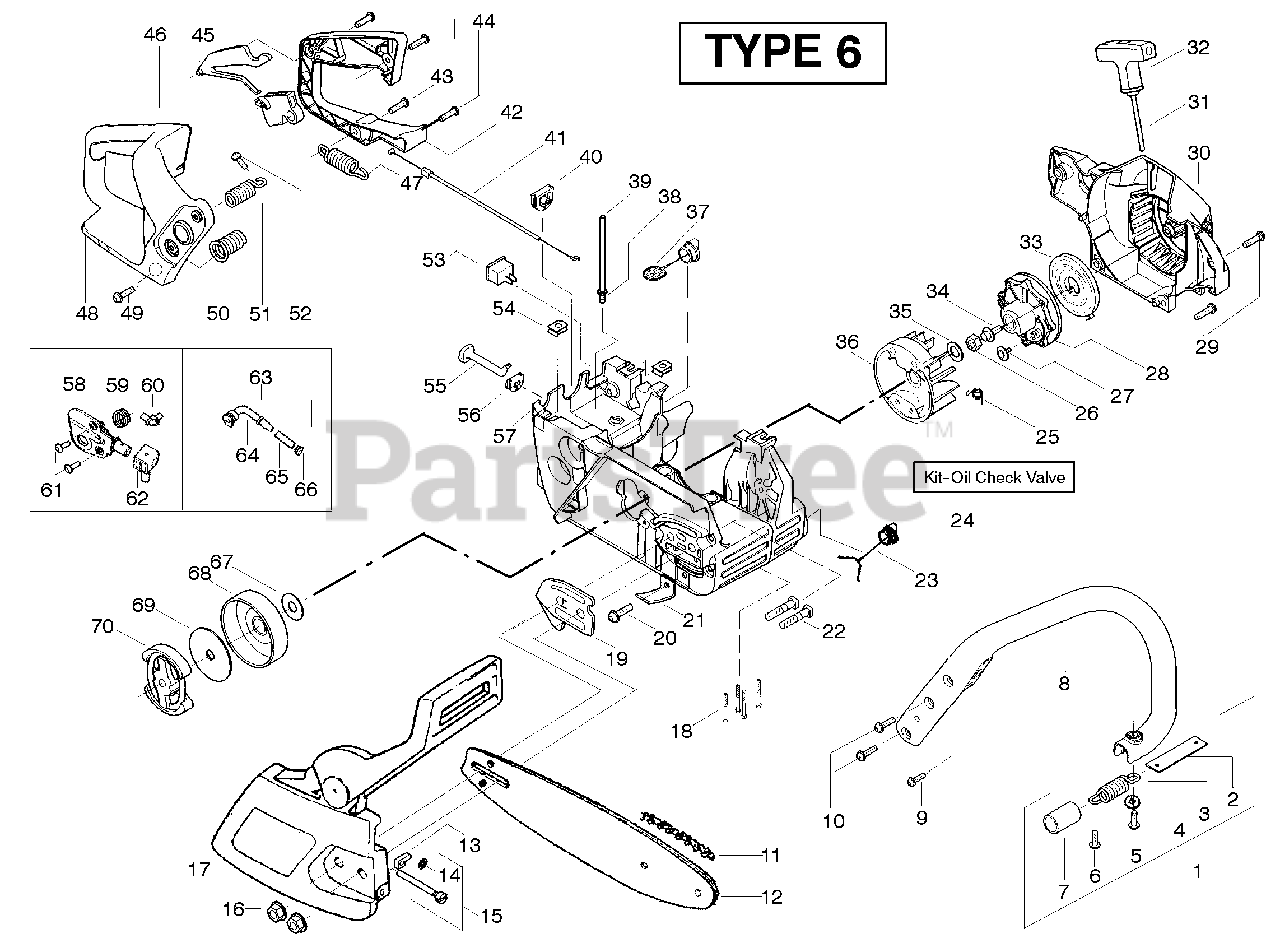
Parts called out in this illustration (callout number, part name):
1	Assy.- Isolator
2	Limiter Strap
3	Spring- Isolator
7	Sleeve-AV Spring
8	Front Handle
11	Chain-18"
13	Pin-Bar Adjust
14	Retainer-Bar Adjust
15	Kit-Bar Adj.
16	Nut-Bar Mounting
17	Kit-Chain Brake
19	Plate-Bar Mounting
21	Chain Catcher
23	Oil Cap Ass’y.
24	Kit-Oil Check Valve
25	Spring-Starter Dog
26	Nut- Flywheel
28	Starter Pulley
32	Starter Handle
33	Recoil Spring
35	Washer- Flywheel
36	Assy- Flywheel
37	Fuel Cap Ass’y.
38	Fitting- fuel line
39	Kit-Fuel line (large)
40	Grommet-Cable
41	Cable-Throttle
42	Cover-Rear Handle
45	Throttle Lockout
46	Trigger-Throttle
47	Spring- Isolator
48	Handle - Rear
50	Assy. Isolator - lower
51	Kit- Isolator (Upper)
54	Nut- "U"-Type
57	Assy-Chassis
58	Kit - Oil Pump
59	Gear-Worm Spring
60	Elbow-Oil Pickup
63	Assy-Oil Pick-up
64	Pick-up Oiler
65	Oil Filter
66	Plug-Oil Filter
67	Washer-Thrust
68	Assy.-Clutch Drum w/bearing
69	Washer-Clutch
